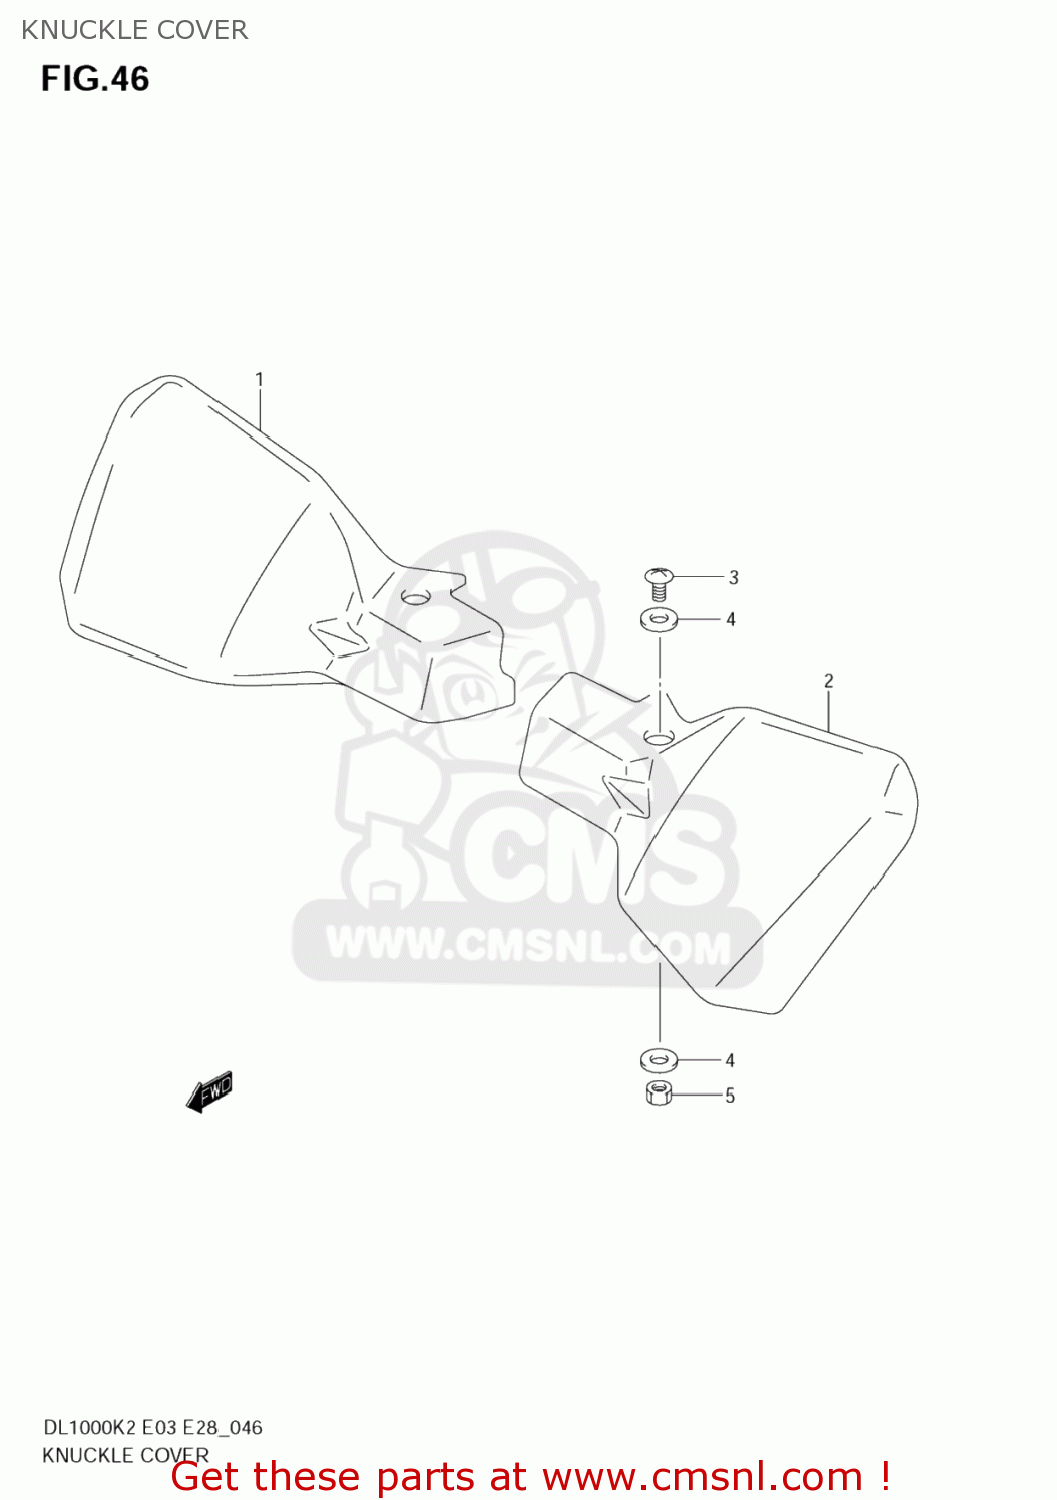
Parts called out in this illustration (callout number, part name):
1	COVER,KNUCKLE,
2	COVER,KNUCKLE,L
3	SCREW
4	WASHER(6.5X16X1.6)
5	NUT 6MM
